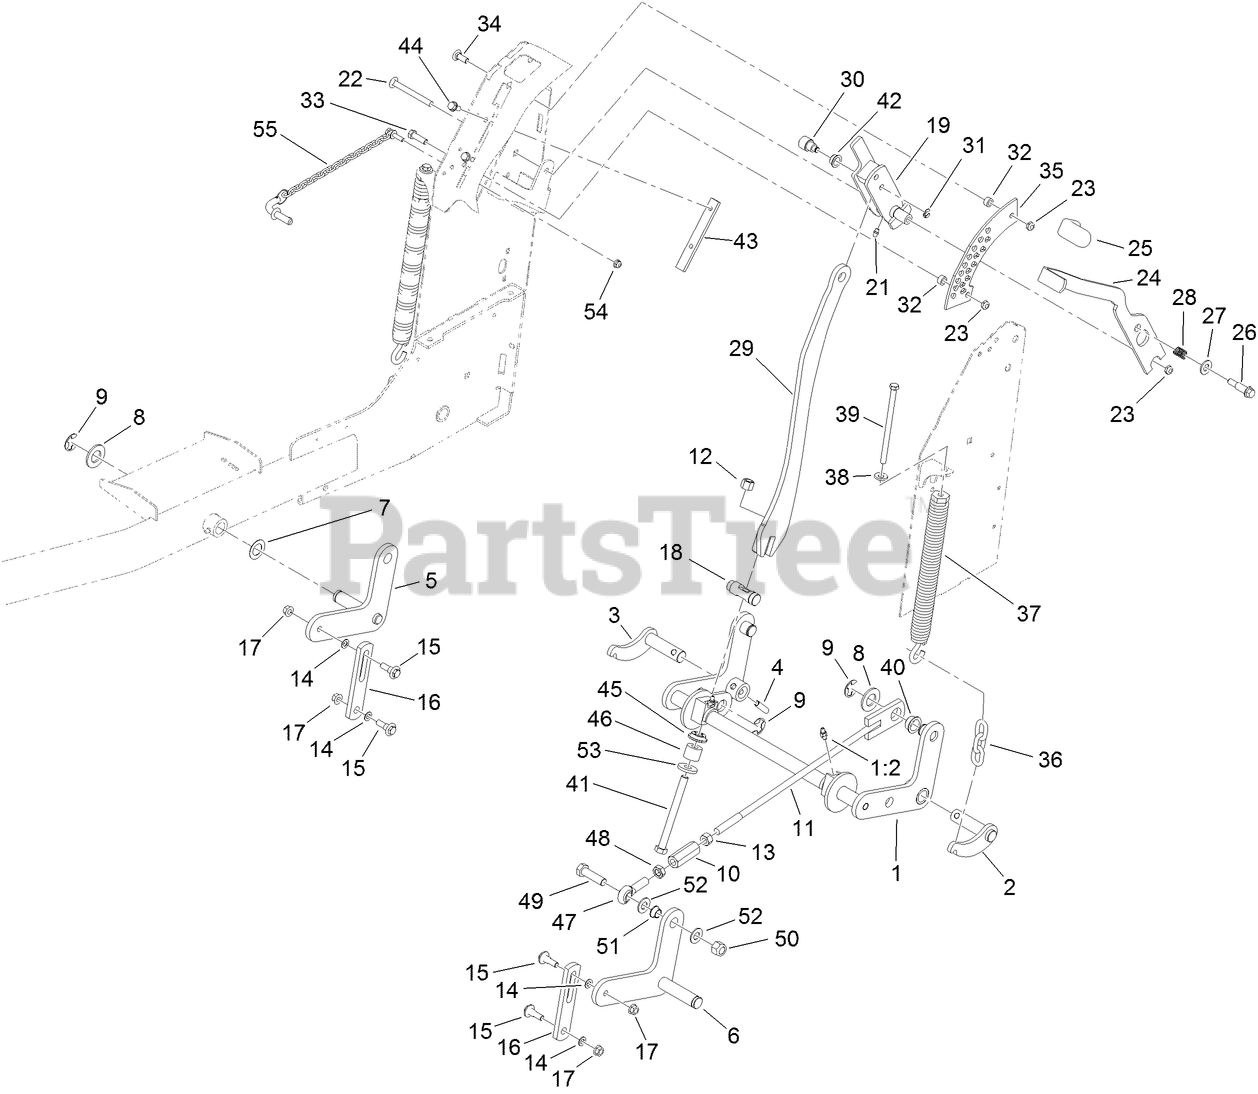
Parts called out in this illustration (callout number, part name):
1	REAR CROSSSHAFT ASM
1:2	FITTING-LUBE, 45 DEG
2	SHAFT-PIVOT, LH
3	SHAFT-PIVOT, RH
4	PIN-SPIRAL
5	RH LIFT ARM ASM
6	LH LIFT ARM ASM
7	WASHER-THRUST
8	WASHER-FLAT
9	RING-RETAINING, EXT
10	LINK-LIFT
11	LIFT ROD ASM
12	NUT-LOCK, NI
13	NUT-HH
14	WASHER
15	SCREW-SHOULDER, HHF
16	LINK-LIFT
17	NUT-HF
18	PIN-HOC
19	HOC HANDLE ASM
21	FITTING-GREASE
22	SCREW-CARR
23	NUT-LOCK, NI
24	LEVER-HOC
25	GRIP-LEVER
26	SCREW-SHOULDER
27	WASHER-FLAT
28	SPRING
29	BAR-LIFT
30	HUB-PIVOT
31	RING-RETAINING
32	SPACER
33	SCREW-HH
34	SCREW-CARR
35	BRACKET-HOC
36	CHAIN-DECKLIFT
37	SPRING-EXTENSION
38	WASHER-BELLEVILLE
39	BOLT-TAP, HH
40	BEARING-FLANGE
41	SCREW-HH
42	BEARING-FLANGE
43	SKID-HANDLE, LIFT
44	SCREW-HWHTF
45	SEAT-SPRING
46	SPRING-URETHANE
47	BALLJOINT-SPHERICAL
48	NUT-JAM
49	SCREW-HH
50	NUT-LOCK, NI
51	BUSHING
52	WASHER-FLAT
53	WASHER
54	NUT-HF
55	HOC PIN ASM
